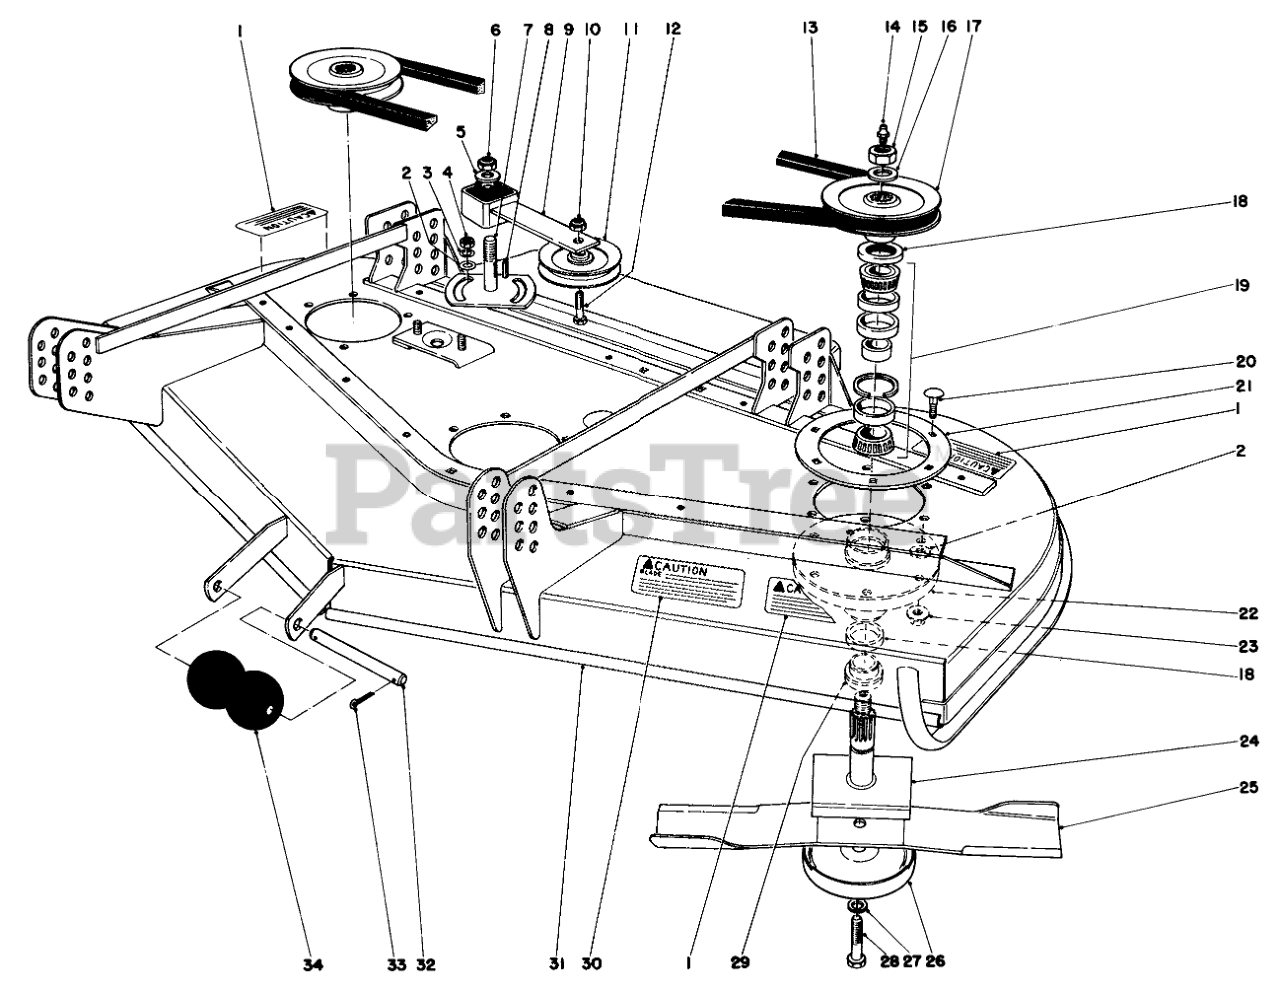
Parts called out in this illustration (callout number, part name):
1	DECAL-CAUTION, BLADE
2	WASHER-FLAT
3	WASHER-LOCK
4	NUT-JAM
5	WASHER-FLAT
6	NUT-LOCK, NI
7	PLATE-IDLER
8	KEY-SQUARE
9	IDLER ARM ASM
10	NUT-HEX
11	Idler Pulley
12	SCREW-HH
13	V-BELT
14	FITTING-GREASE
15	NUT-HEX
16	WASHER
17	PULLEY AND HUB ASM
18	SEAL-OIL
19	BEARING ASM
20	SCREW-CARR
21	SUPPORT-DECK, RING
22	Housing-Spindle
23	NUT-HF
24	SHAFT
25	Blade
26	Cup-Scalp
27	WASHER-LOCK
28	SCREW-BLADE
29	SPACER
30	Decal-Caution
31	CUTTER DECK WA RO
32	SHAFT-ROLLER
33	PIN-COTTER
34	ROLLER
